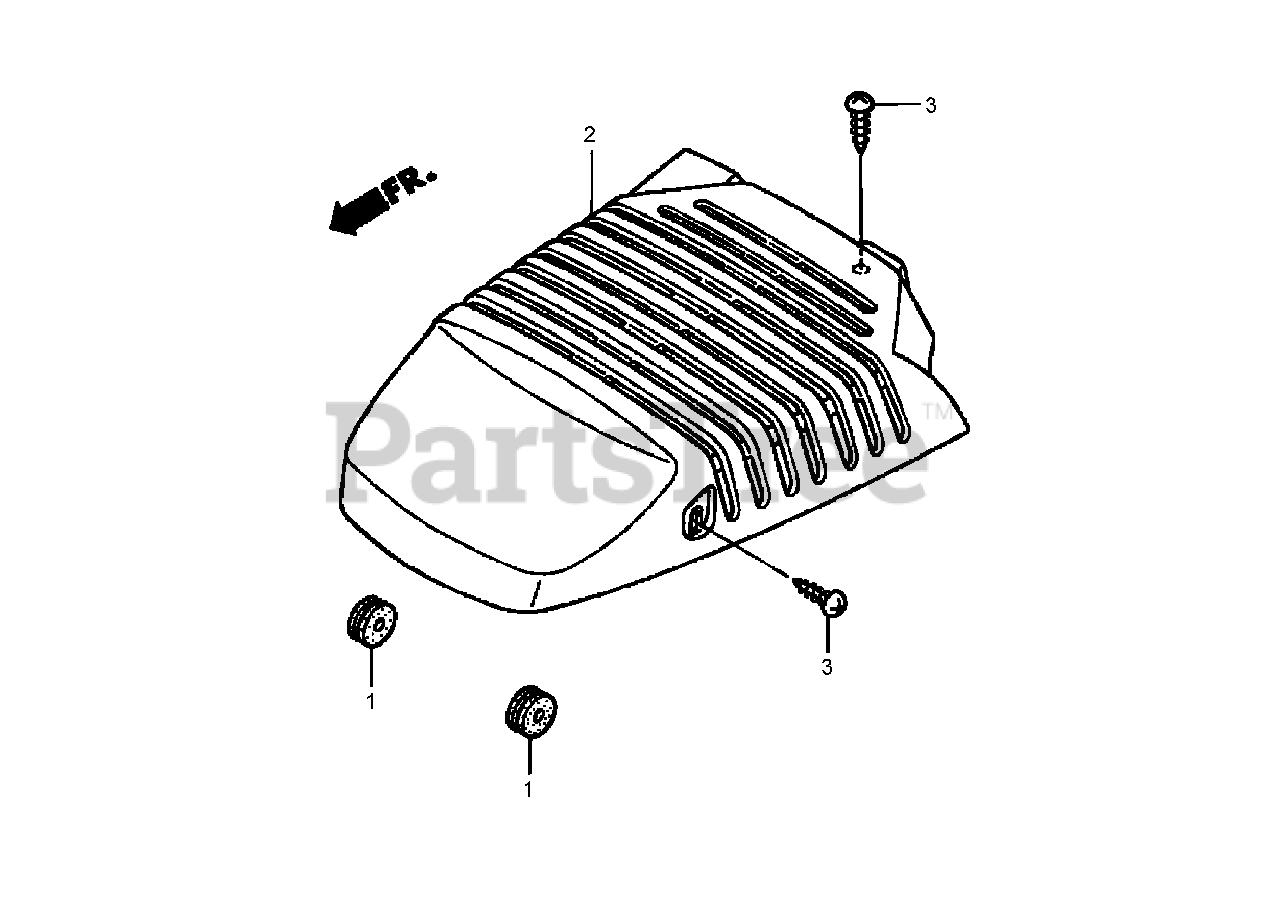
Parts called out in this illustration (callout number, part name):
1	GROMMET-ROD, CHOKE
2	COVER-TOP
3	SCREW-TAPPING (4X16)
